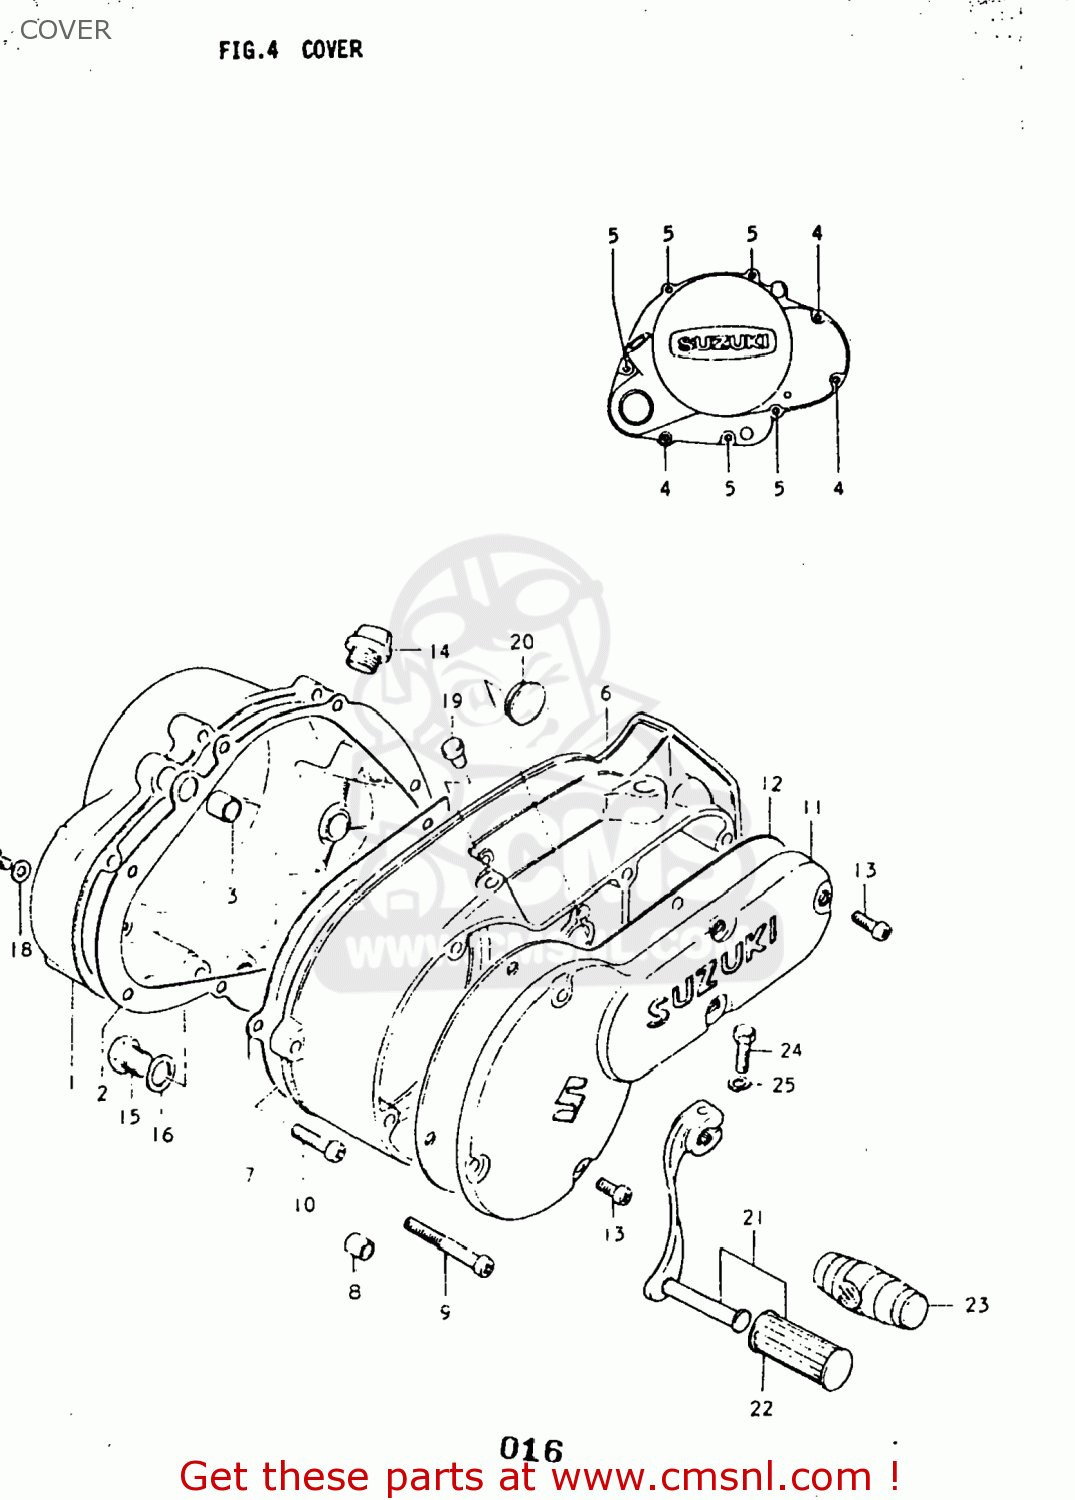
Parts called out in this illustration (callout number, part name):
1	COVER,CLUTCH
2	GASKET,CLUTCH COVER (MCA)
3	PIN
4	SCREW
5	SCREW
6	COVER
7	GASKET,CLUTCH COVER (NAS)
8	PIN
9	SCREW
10	SCREW
11	CAP,MAGNETO INSPECTION
12	GASKET,MAGNETO INSPECTION (MCA)
13	SCREW
14	PLUG
15	PLUG
16	GASKET(14X19.2X2) (NAS)
17	SCREW(6X10)
18	GASKET(6.2X11X1) (NAS)
19	CAP
20	CAP(OD:26)
21	LEVER ASSEMBLY,GEAR SHIFTING
22	RUBBER,GEAR SHIFT PEDAL
23	RUBBER,GEAR SHIFT PEDAL
24	BOLT
25	LOCK WASHER
